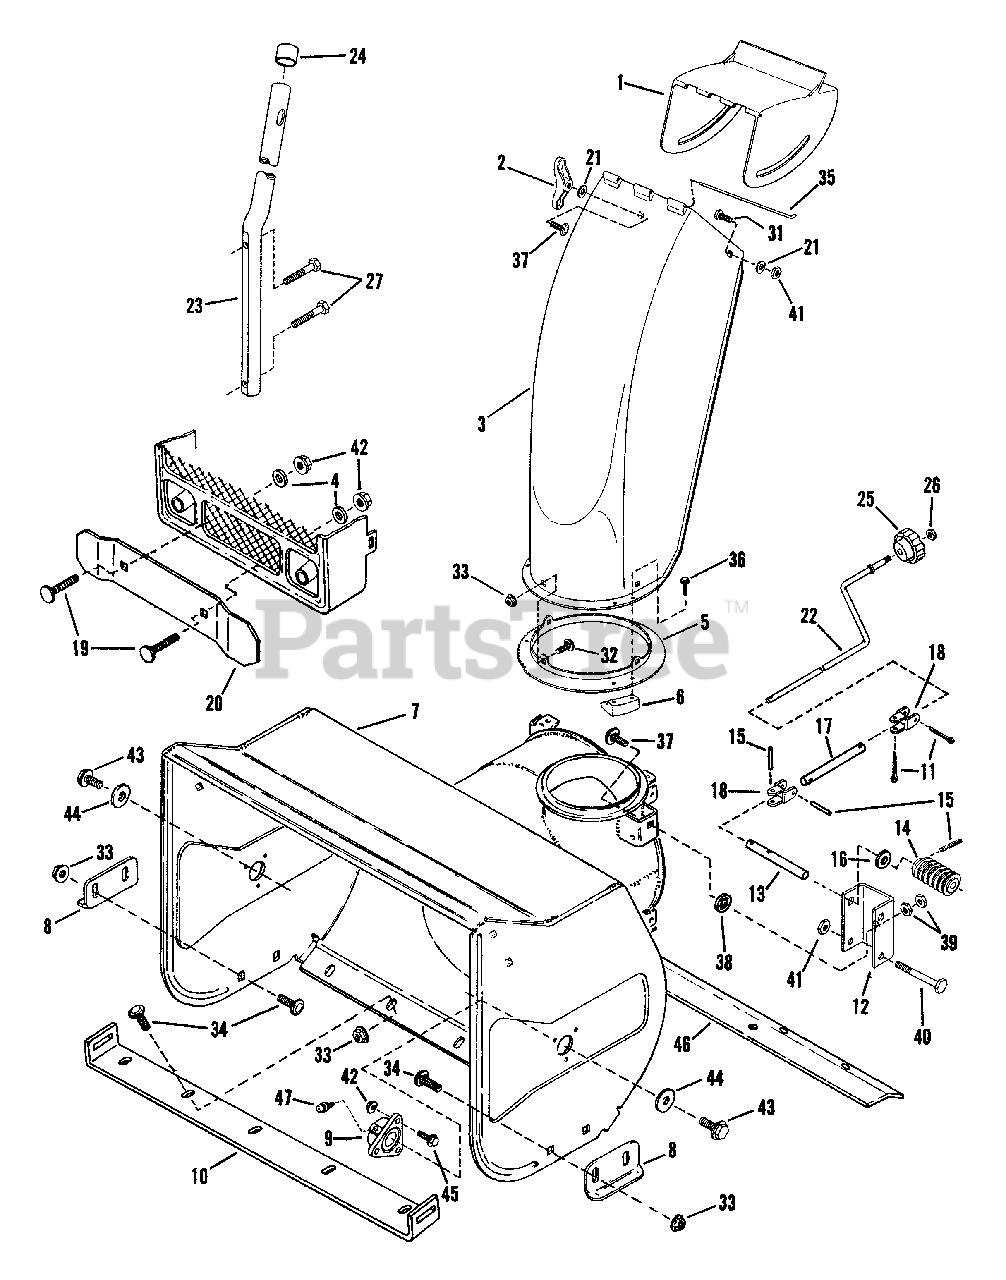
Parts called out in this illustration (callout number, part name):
1	DEFLECTOR, Discharge
2	WING-NUT
3	CHUTE, Discharge
4	WASHER, 1/4 Flat
5	RING, Chute
6	RETAINER, Chute Ring
7	HOUSING,Blower (36")
8	SHOE, Skid
9	BEARING, Auger Shaft
10	BLADE, Scraper
11	PIN, 1/8x1-1/4" Cotter
12	BRACKET, Worm
13	SHAFT, Worm
14	WORM
15	ROLL-PIN, 1/8x3/4
16	WASHER, Spring Steel
17	ROD, Connect
18	CONNECTOR
19	BOLT, 1/4-20x5/8" Flat Head Carriage
20	DEFLECTOR, Exhaust
21	WASHER, 5/16 Flat
22	CRANK, Chute
23	BRACE, Chute Crank
24	CAP, Crank Brace
25	KNOB, Chute Crank
26	NUT, 5/16-18 Hex Lock
27	SCREW, 5/16-18x1-1/2 Self Tap
31	SCREW. 5/16-24x3/4" Hex Head Cap
32	BOLT, 5/16-18x5/8" Carriage
33	NUT, 5/16-18 Hex Flange
34	BOLT, 5/16-18x3/4" Carriage
35	PIN, Hinge
36	SCREW,#10-24x5/8" Self-tapping
37	BOLT, 5/16-18x1" Carriage
38	RETAINER, Bolt
39	NUT, 5/16-18 Hex
40	SCREW, 5/16-24x2-1/2 Hex Head Cap
41	NUT, 5/16-24 Hex Lock
42	NUT, 1/4-20 Hex Flange Lock
43	SCREW, 3/8-16x1/2" Self Tap.
44	WASHER, 3/8" Flat
45	BOLT, 1/4-20x5/8" Hex Flange Lock
46	BAR, Stiffener
47	FITTING, Lube (Press fit for .187 hole-no ball)
